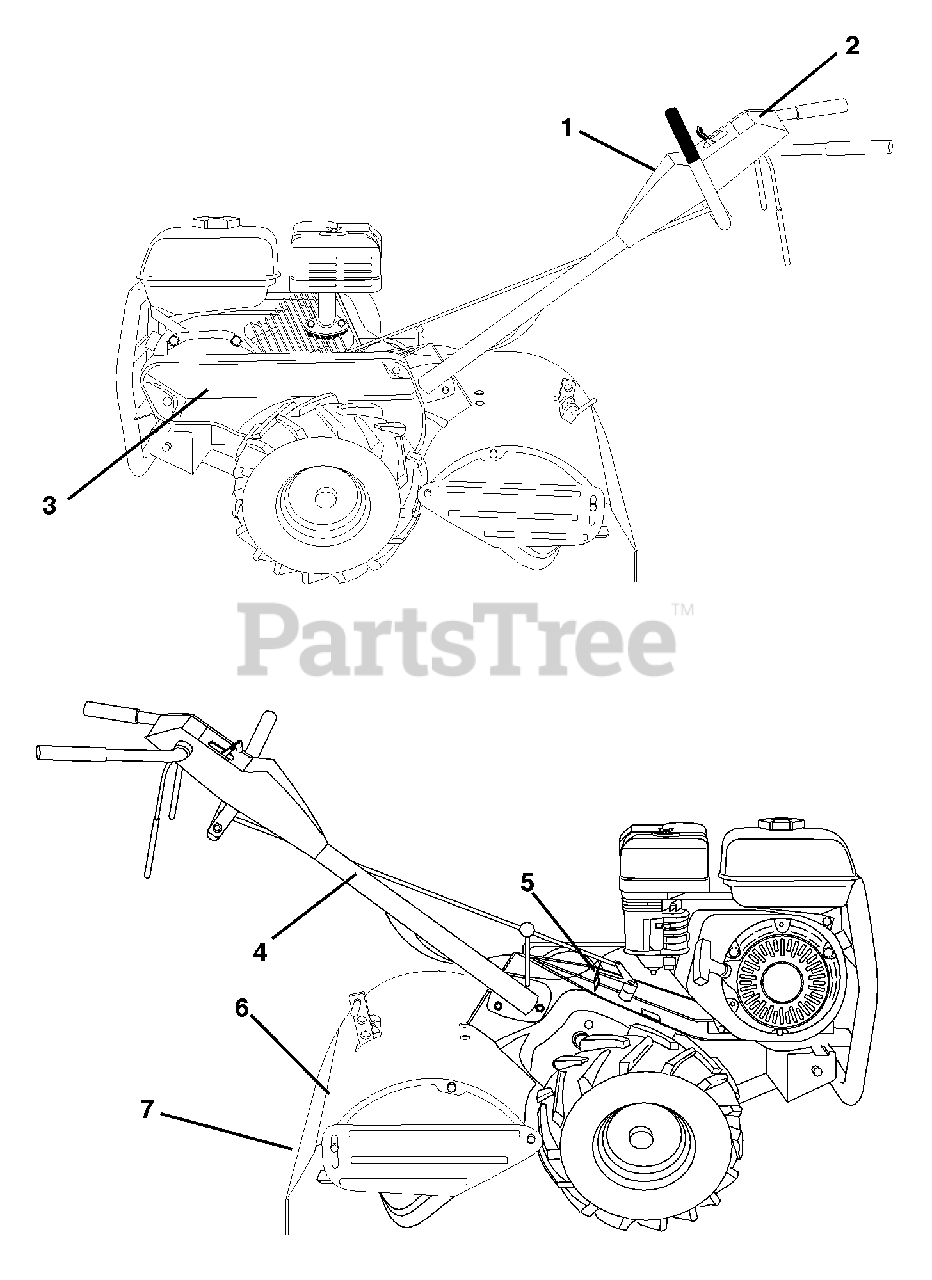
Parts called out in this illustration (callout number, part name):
1	Decal, Logo
2	Decal, Logo
3	Decal, Logo
4	Decal, Hand Placement
5	Decal, Shift Indicator
6	Decal, Warning Till
7	Decal, Warning, Rotating Tines
